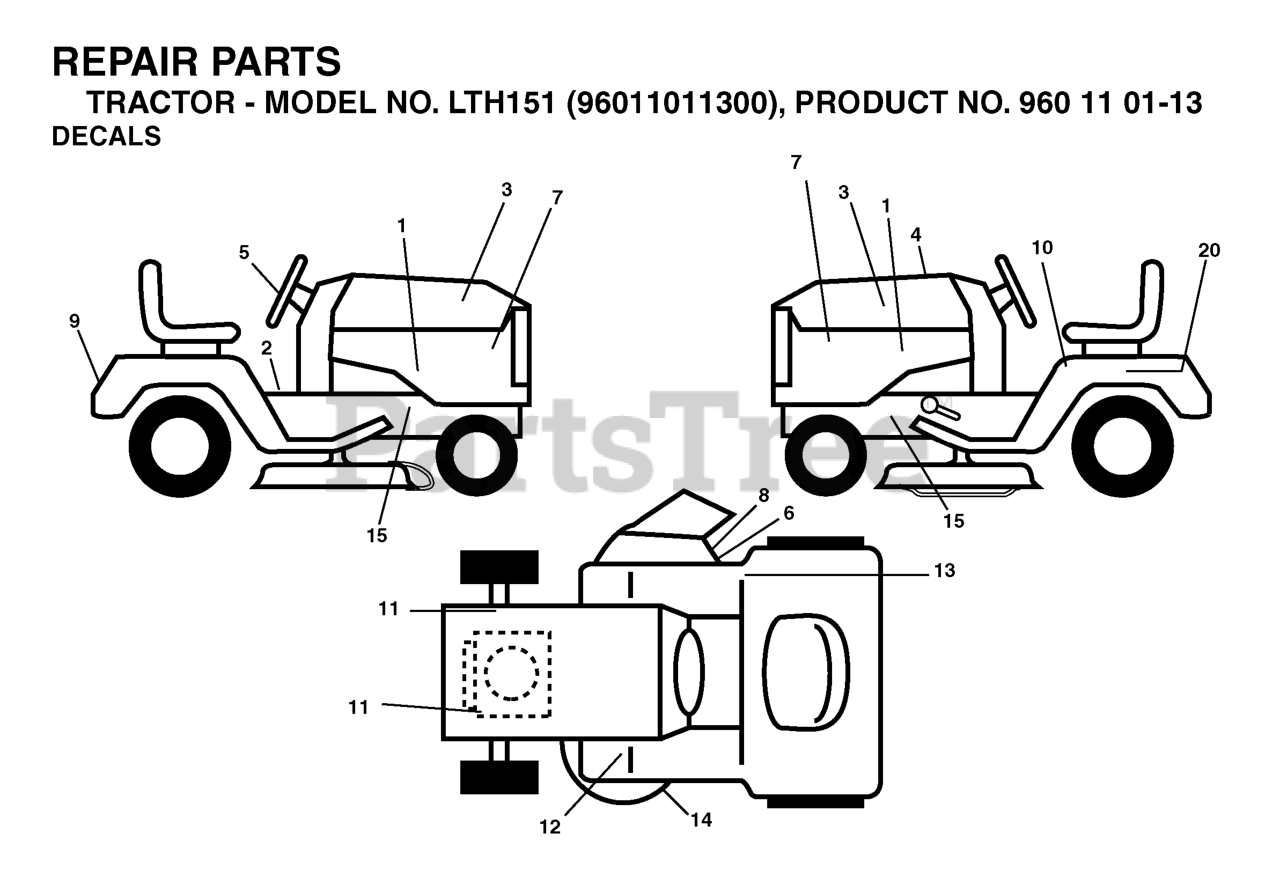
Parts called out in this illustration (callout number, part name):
2	DECAL PARK BRAKE
5	DECAL.STEERING.HUSQ.BLUE
6	DECAL, DEFLECT WARNING
7	DECAL.HOOD.HUSQVARNA.INTERNATI
8	DECAL.INTERNATIONL.CUTFINGER
10	LABEL
12	DECAL
13	Decal, Fender 100 DB/CE
14	DECAL.V-BELT.SCHEMATIC.36/38/9
20	DECAL BTRY SYMBOLS
